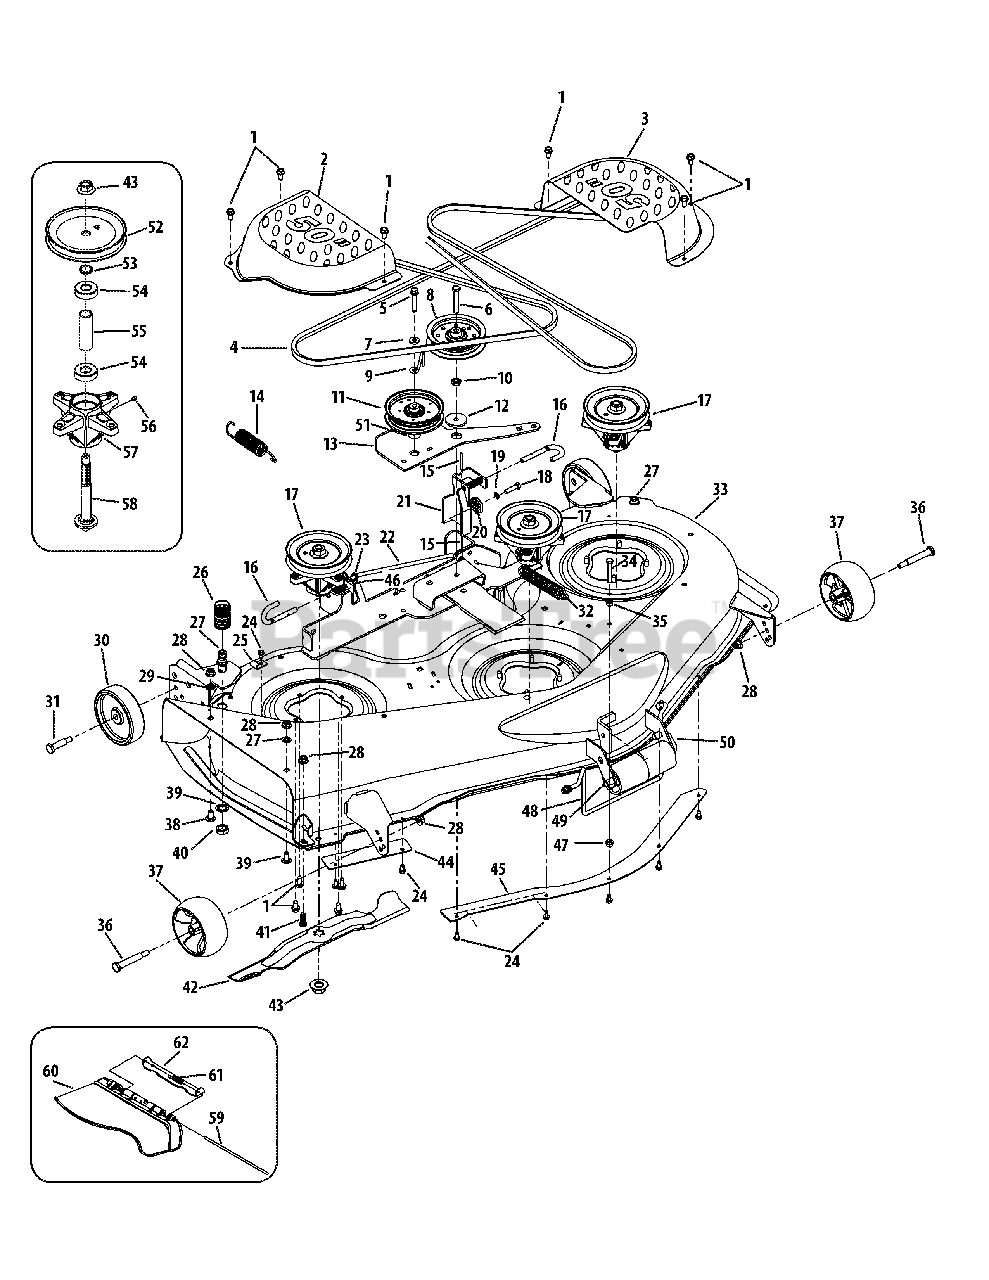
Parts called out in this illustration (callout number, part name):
1	Hex Washer Screw, 5.16-18 x .750
2	Belt Cover, RH
3	Belt Cover, LH
4	V-Belt
5	Hex Washer Screw, 3.8-16 x 1.875
6	Hex Screw, 3.8-16 x 2.25
7	Flat Washer, .407 x .812 x .135
8	Idler Pulley
9	Belt Keeper Rod
10	Jam Nut, 7.16-20
11	Idler Pulley
12	Shoulder Spacer, .8840 x .190
13	Idler Arm Bracket
14	Extension Spring, 1.15 x 5.99
15	Cotter Pin, 1.8 x 1.25
16	Deck Handle Rod
17	Spindle Assembly
18	Hex Screw, 5.16-18 x 1.25
19	Lock Washer, 5.16
20	Deck Adjustment Gear
21	Deck Hanger Bracket Assembly
22	Deck Support Rod
23	Washer, .375 x .70 x .030
24	Hex Washer Screw, 1.4-20 x .500
25	Hook Retainer Bracket
26	Water Nozzle Adapter
27	Deck Water Nozzle
28	Flange Lock Nut, 3.8-16
29	Push Nut, 3.8
30	Deck Wheel
31	Shoulder Bolt, 3.8-16 x .496 x 1.525
32	Extension Spring, 1.0 X 6.10
33	Deck Assembly
34	Hex Screw, 5.16-18 x 2.00
35	Hex Nut, 5.16-18
36	Shoulder Bolt, 3.8-16 x .496 x 2.50
37	Deck Wheel
38	Carriage Bolt, 3.8-16 x .75
39	Lock Washer, 5.8
40	Hex Nut, M16-1.5
41	Hex Screw, 3.8-16 x 1.00
42	2-in-1 Blade
43	Flange Nut, 5.8-18
46	Bow-Tie Cotter Pin
47	Flange Lock Nut, 5.16-18
48	Torque Rod
49	Cotter Pin, 3.32 x 1.00
50	Roller Pin
51	Spacer, .406 x 1.00 x .38
52	Deck Pulley
53	Spacer, .750 x 1.150 x .230
54	Ball Bearing, .787 x 1.85
55	Spacer, .800 x 1.100 x 1.5300
56	Lube Fitting
57	Spindle Housing
58	Spindle Shaft
59	Hinge Pin, .3175 x 14.06
60	Chute Assembly
61	Torsion Spring, .44 x 2.0
62	Chute Bracket
